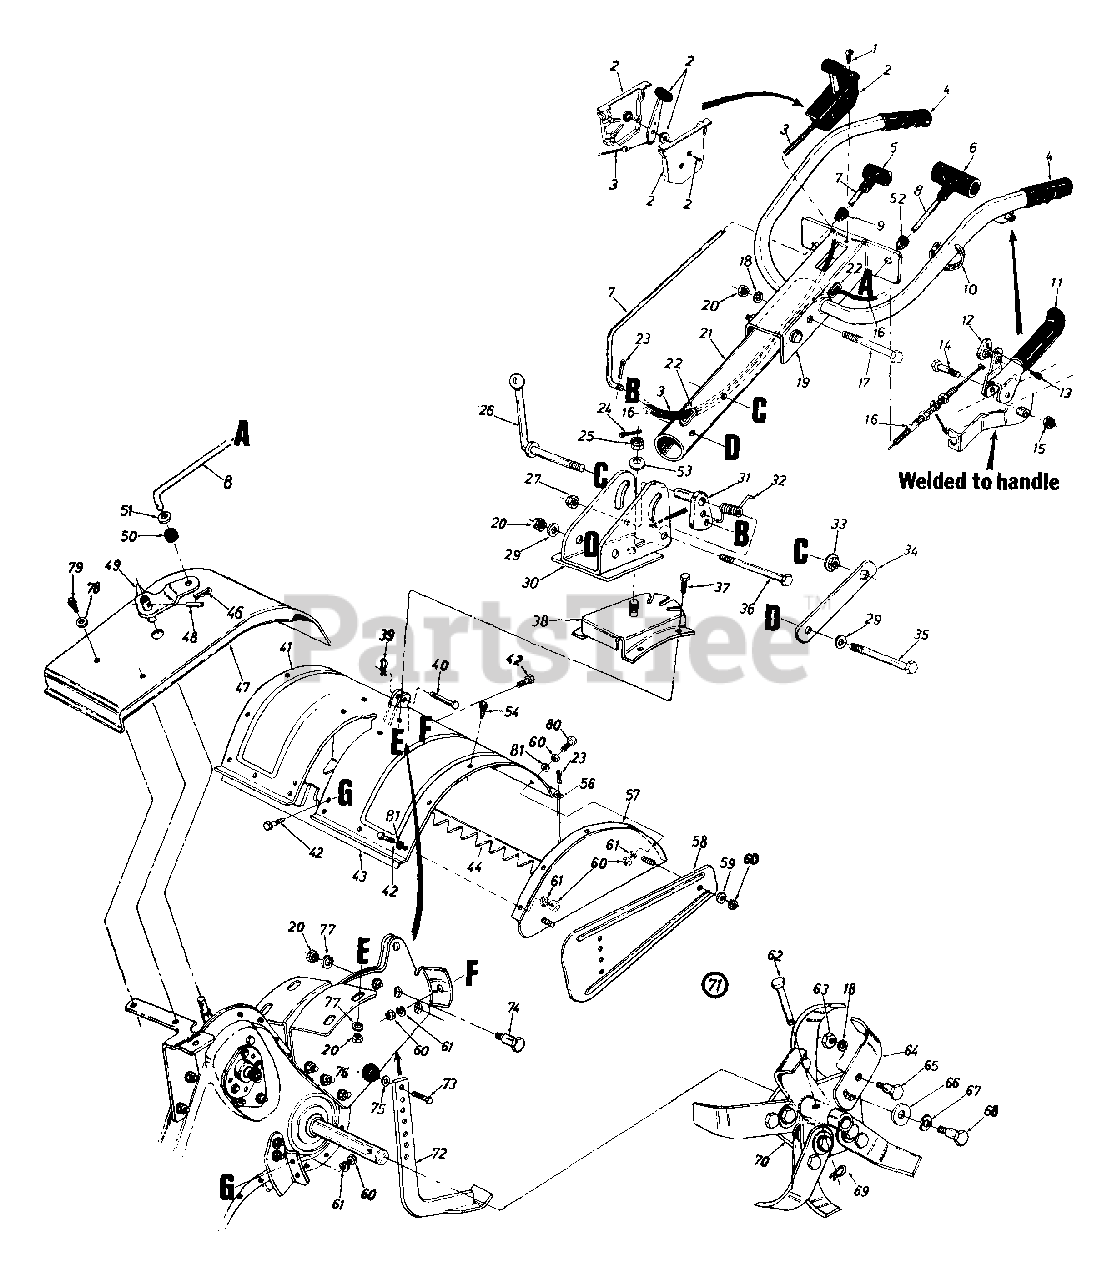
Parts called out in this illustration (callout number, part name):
1	Truss Mach. AB-Tap. Scr. #10 x .50" Lg.
2	Throttle Control Box Ass'y.
3	Throttle Control Wire
4	Handle Grip
5	Small "T" Knob
6	Large "T" Knob
7	Clutch Rod
8	Control Rod 37" Lg.
9	Snap On Bushing 3/8" Dia.
10	Cable Tie-Self Clinching
11	Clutch Grip Ass'y. - L.H.
12	Barrel Cable Hold Down
13	Hex B-Tap Scr. #10 x .44" Lg.
14	Hex Bolt 3/8-24 x 2.25" Lg.
15	Hex Jam L-Nut 3/8-24 Thd.
16	Clutch Control Cable 53" Lg.
17	Hex Bolt 3/8-16 x 3.00" Lg.
18	L-Wash. 3/8" I.D. - H.D.
19	Handle Ass'y.
20	Hex Nut 3/8-16 Thd.
23	Cotter Pin 3/32" Dia. x .75" Lg.
24	Cotter Pin 3/32" Dia. x 1.25" Lg.
25	Hex Slotted Nut 5/8-18 Thd.
26	Handle Adj. Crank
27	Hex Cent. L-Nut 3/8-16 Thd.
29	Bell-Wash. .4" I.D. x .87" O.D.
30	Handle Pivot Bracket
31	Positioner Crank Ass'y.
32	Spring Handle Adj. (Torsion)
33	Hex Flange Nut 3/8-24 Thd.
34	Bracket Hex Nut Retainer
35	Hex Bolt 3/8-16 x 3.25" Lg.
36	Hex Bolt 3/8-16 x 3.00" Lg. - Gr. 8
37	Hex Bolt 3/8-16 x .75" Lg.
40	Clevis Pin .375" Dia.
43	Bracket Reinforcement - 18"
46	Intern. Cotter Pin 5/16" Dia.
49	Shifting Crank Ass'y.
50	Rubber Washer .33" I.D.
51	Fl-Wash. .4" I.D. x 1.25" O.D.
52	Snap On Bushing 1/2" Dia.
53	Bell-Wash. .63" I.D. x 1.25"
54	Hex Wash. Tap Scr.
56	Tiller Flap Rod
57	End Cover Ass'y.
60	Hex Nut 5/16-18 Thd.
61	L-Wash. 5/16" I.D.
62	Clevis Pin .375" Dia.
63	Hex Nut 3/8-24 Thd.
64	13" Dia. Articulating Tine
65	Shld. Bolt 1/2" Dia. x .175
66	Fl-Wash. .51" I.D. x 1.50"
67	Bell-Wash. .515" I.D. x 1.14"
68	Shld. Bolt 1/2" Dia. x .320
69	Intern. Cotter Pin
70	Tine Adapter Ass'y. 18"
71	Tine Ass'y. Comp. 18"
72	Depth Bar Ass'y.
73	Hex Bolt 3/8-16 x .75" Lg.
74	Shld. Bolt 1/2" I.D. x .62" Lg.
75	Fl-Wash. 3/8" I.D. x 5/8" O.D.
76	Ball Knob
77	L-Wash. 3/8" I.D.
78	Fl-Wash. .281" I.D. x .62"
79	Hex Wash. Self-Tap Scr. 1/4-20 x .50" Lg.
80	Hex Bolt 5/16-18 x 1-1/4" Lg.
81	Fl-Wash. .344" I.D. x .62 O.D.
